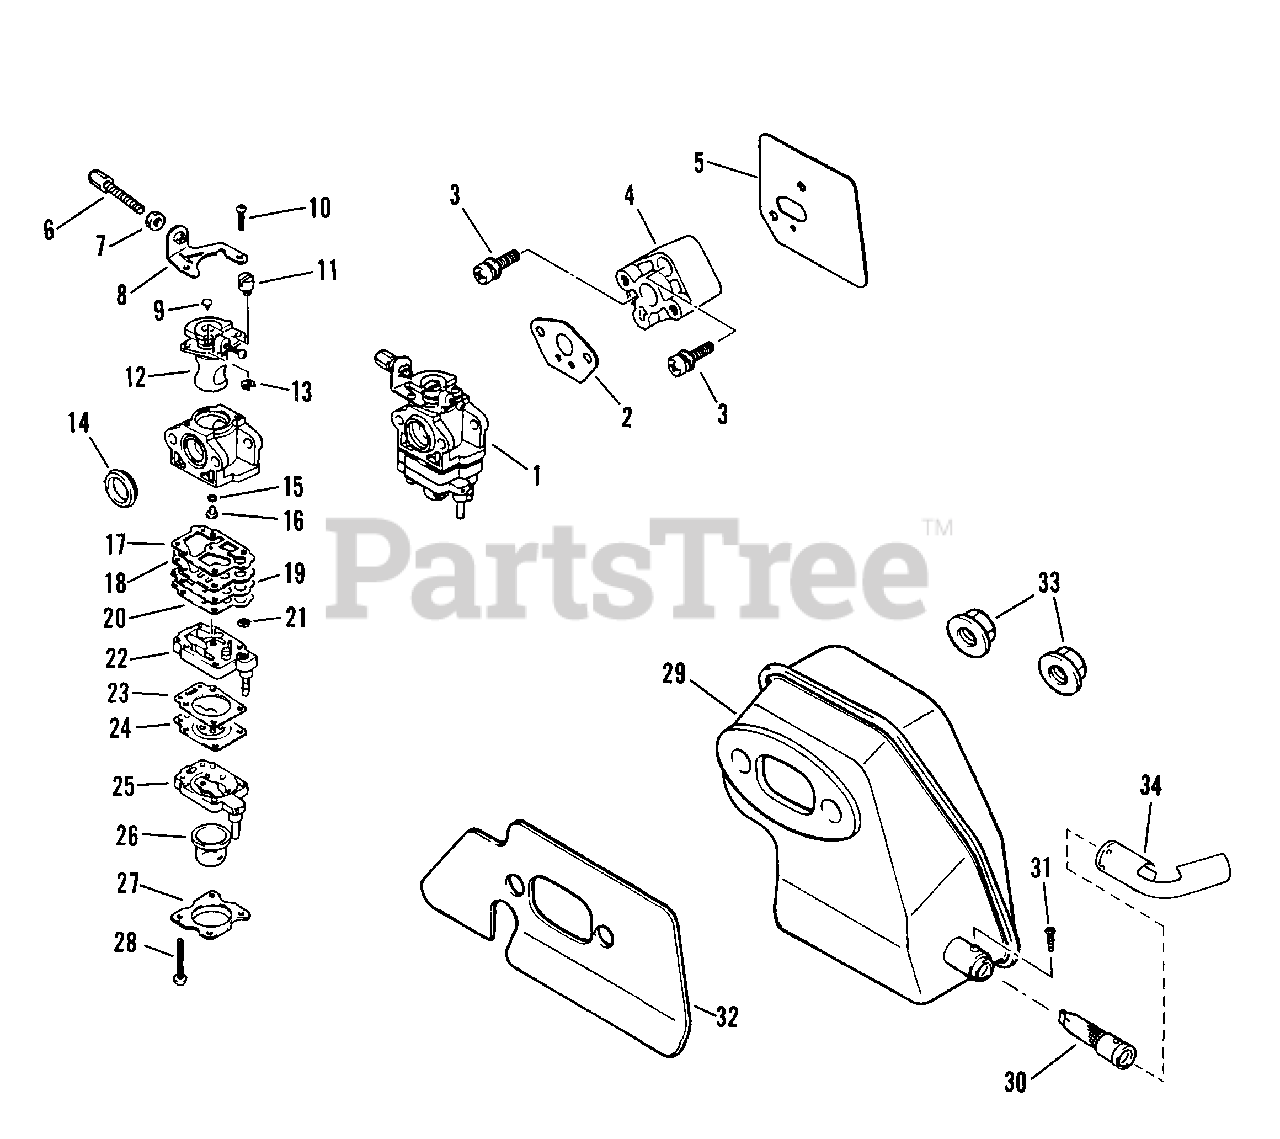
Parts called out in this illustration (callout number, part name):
1	ASSEMBLY, Carburetor
2	GASKET, Carburetor
3	SCREW/WASHER
4	INSULATOR
5	GASKET, Insulator
7	NUT
8	BRACKET
11	HOLDER, Wire
12	VALVE, Throttle
14	PACKING
16	JET, Main
18	DIAPHRAGM
22	BODY, Pump
24	DIAPHRAGM
26	ASSEMBLY, Primer Pump
29	MUFFLER
30	SPARK ARRESTER
32	GASKET, Muffler
33	NUT, Flange
34	EXHAUST, Elbow
